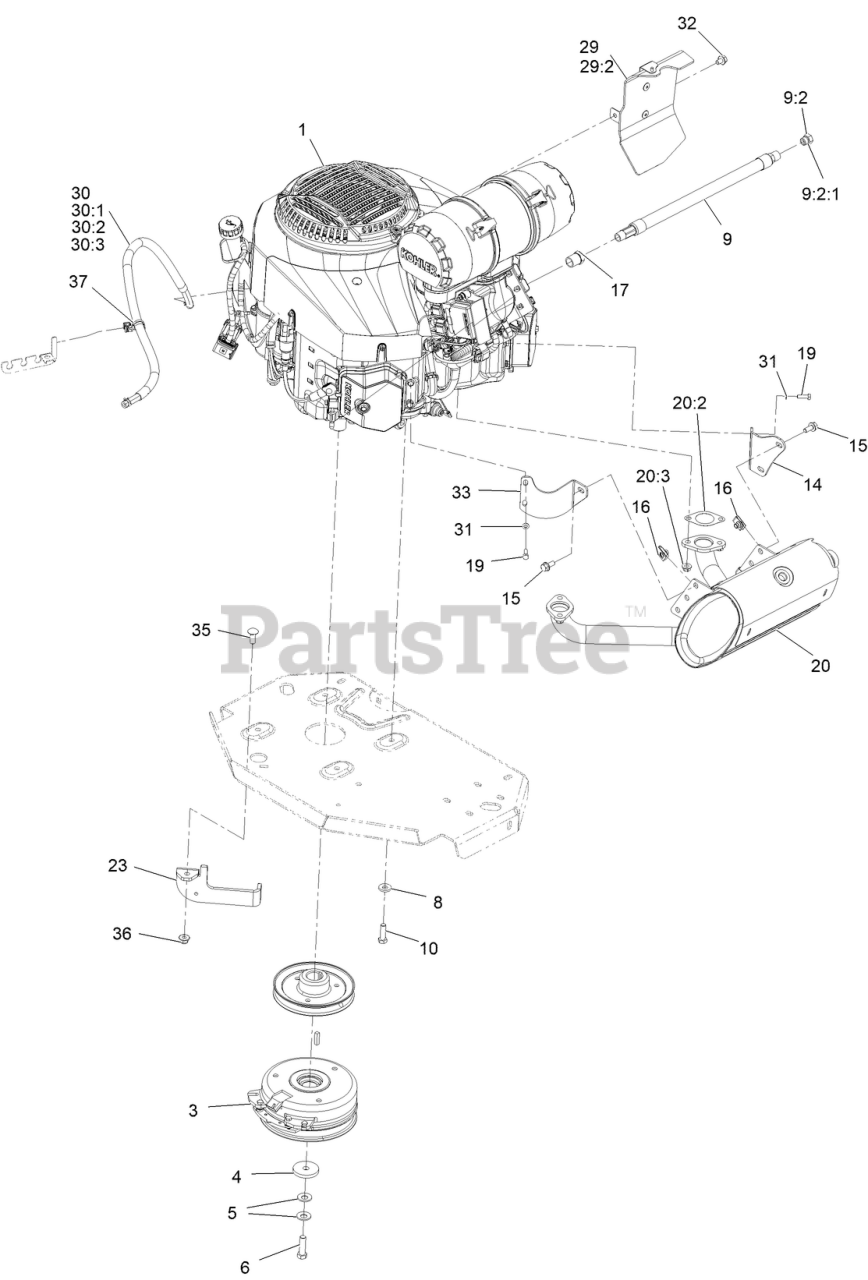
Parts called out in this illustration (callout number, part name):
3	CLUTCH KIT
4	WASHER-CLUTCH
5	WASHER-SPRING
6	SCREW-HH 7/16-20 X 1 1/2 W/LOCTITE
8	WASHER-BELLEVILLE
9	OIL DRAIN HOSE ASM
9:2	PLUG-HH
9:2:1	O-RING
10	SCREW-HH
14	BRACKET-MUFFLER
15	SCREW-HHF
17	BUSHING
19	SCREW-HH M6-1 X 20Mm W/Patch
20	MUFFLER-940-980 KOH EFI
20	MUFFLER KIT
20:2	GASKET-EXHAUST
20:3	NUT-FLANGE, LOCK
23	Bracket-Clutch Anchor
29	Baffle Kit
29:2	SCREW-HWH
29:2	Screw-HHF
30	FUEL LINE ASM
30:1	HOSE-FUEL
30:2	SLEEVE, THERMAL
30:3	CLAMP-HOSE
31	WASHER-SPRING
32	Screw-HHF
33	BRACKET-MUFFLER, FRONT
35	SCREW-CARR
36	NUT-HF, NI
37	Clip-Edge
